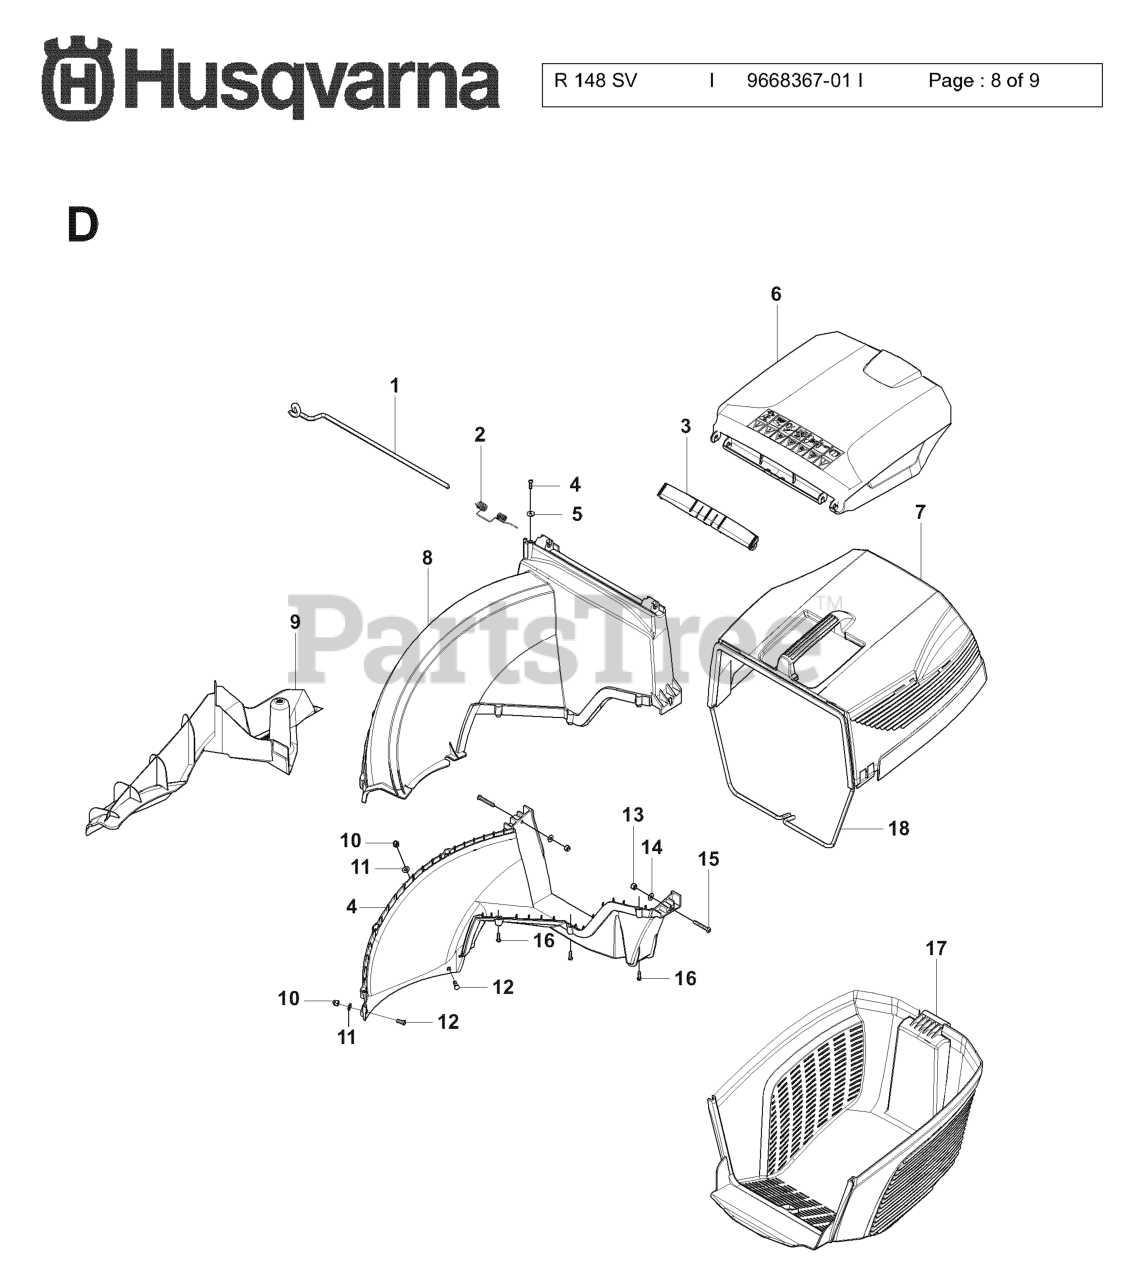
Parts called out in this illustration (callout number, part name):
2	SPRING SAFETY FLAP A009
4	CHUTE LOWER A009
6	HATCH REAR DISCHARGE
7	GRASSBAG UPPER
8	CHUTE UPPER A009
16	SCREW ITXPANT T50X16 ZN/FE (A
17	GRASSBAG LOWER
